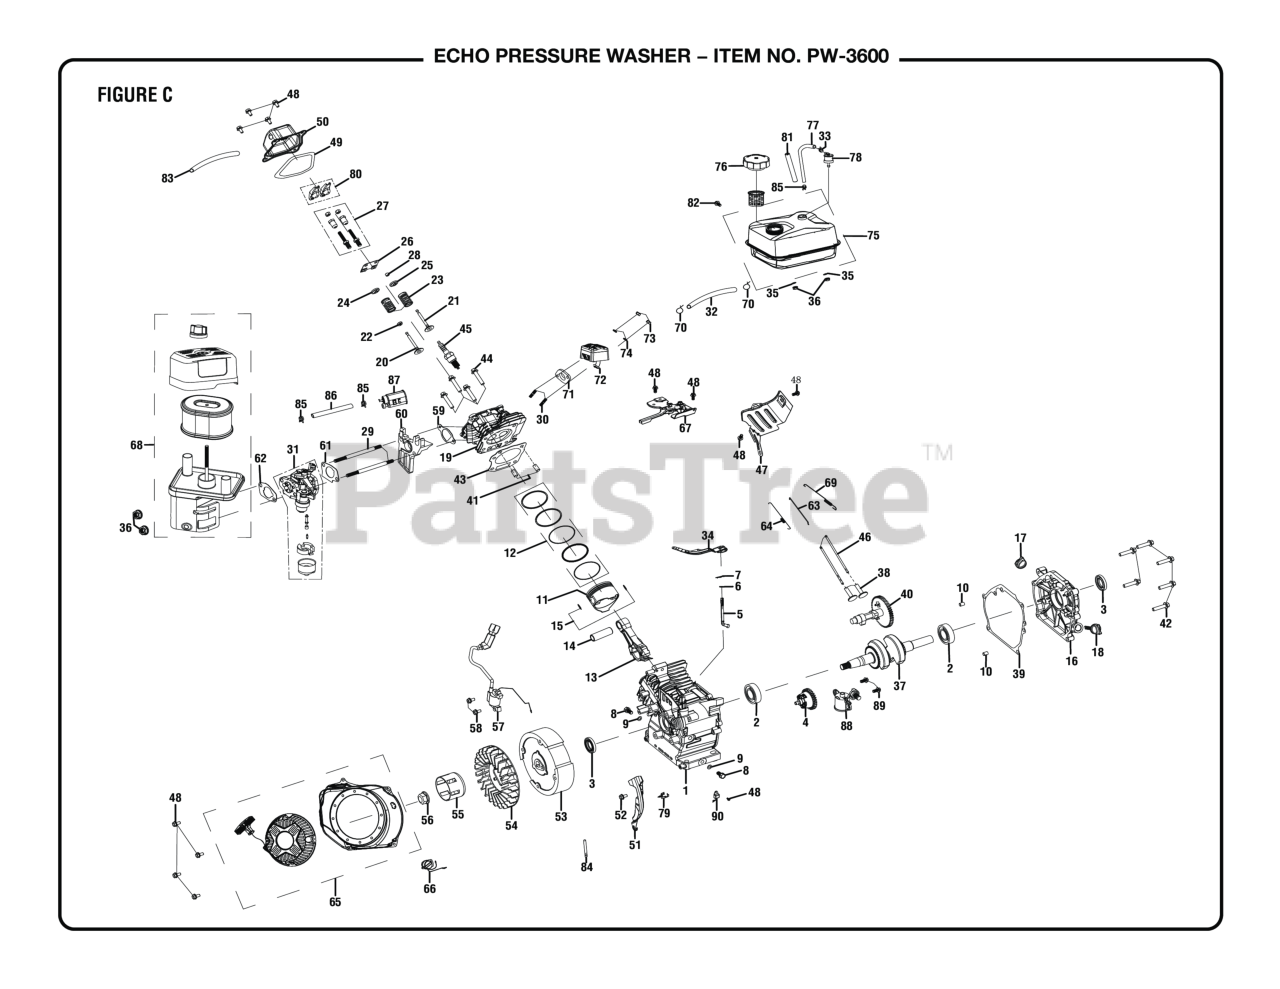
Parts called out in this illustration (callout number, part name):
1	CRANKCASE
2	BEARING, BALL
3	SEAL, OIL
4	ASSY., GOVERNOR
5	SHAFT, GOVERNOR ARM
7	PIN, LOCK
8	BOLT, DRAIN PLUG
9	WASHER, DRAIN PLUG
10	DOWEL PIN, CASECOVER
12	SET, PISTON SCRAPER RING
13	ASSY., CONNECTING ROD
14	PIN, PISTON
15	CLIP, PISTON
16	COVER, CRANKCASE
17	PLUG, OIL
18	DIPSTICK
19	CYLINDER HEAD
20	VALVE, INTAKE
21	VALVE, EXHAUST
22	RETURNER, INTAKE VALVE
23	SPRING,VALVE
24	SEAT, INTAKE VALVE SPRING
25	SEAT, EXHAUST VALVE SPRING
26	PLATE,PUSH ROD GUIDE
27	BOLT, ROCKER ARM
29	BOLT, STUD
30	BOLT, STUD
31	ASSY., CARBURETOR
32	HOSE, FUEL
33	CLIP, FUEL HOSE
34	ARM, GOVERNOR
37	ASSY., CRANKSHAFT
38	LIFTER, VALVE
39	GASKET, CRANKCASE COVER
40	ASSY., CAMSHAFT
41	PIN, DOWEL
43	GASKET, CYLINDER HEAD
45	PLUG, SPARK
46	ROD, PUSH
49	GASKET, VALVE COVER
50	COVER, VALVE
51	SHIELD, WIND
53	ASSY., FLYWHEEL
54	FAN, RECOIL STARTER
55	PULLEY, STARTER
57	MODULE, IGNITION
59	GASKET, INTAKE
60	INSULATOR, CARBURETOR
61	GASKET, CARBURETOR
63	ROD, GOVERNOR
64	SPRING, THROTTLE RETURN
65	ASSY., RECOIL STARTER
67	SHROUD, UPPER
68	AIR CLEANER
69	SPRING,GOVERNOR
70	CLIP, FUEL HOSE
71	GASKET, EXHAUST
74	WASHER, SPRING
75	ASSY., FUEL TANK
76	CAP, FUEL
77	PIPE, CONNECTING
78	ASSY., CHOKE
80	ARM, ROCKER
81	PROTECTOR, VENTILATION TUBE
83	TUBE, BREATHER
84	CLIP, WIRE HARNESS
85	CLIP, FUEL HOSE
86	PIPE, CONNECTING
87	CANNISTER, CARBON
88	SWITCH, OIL LEVEL
90	AMPLIFIER
